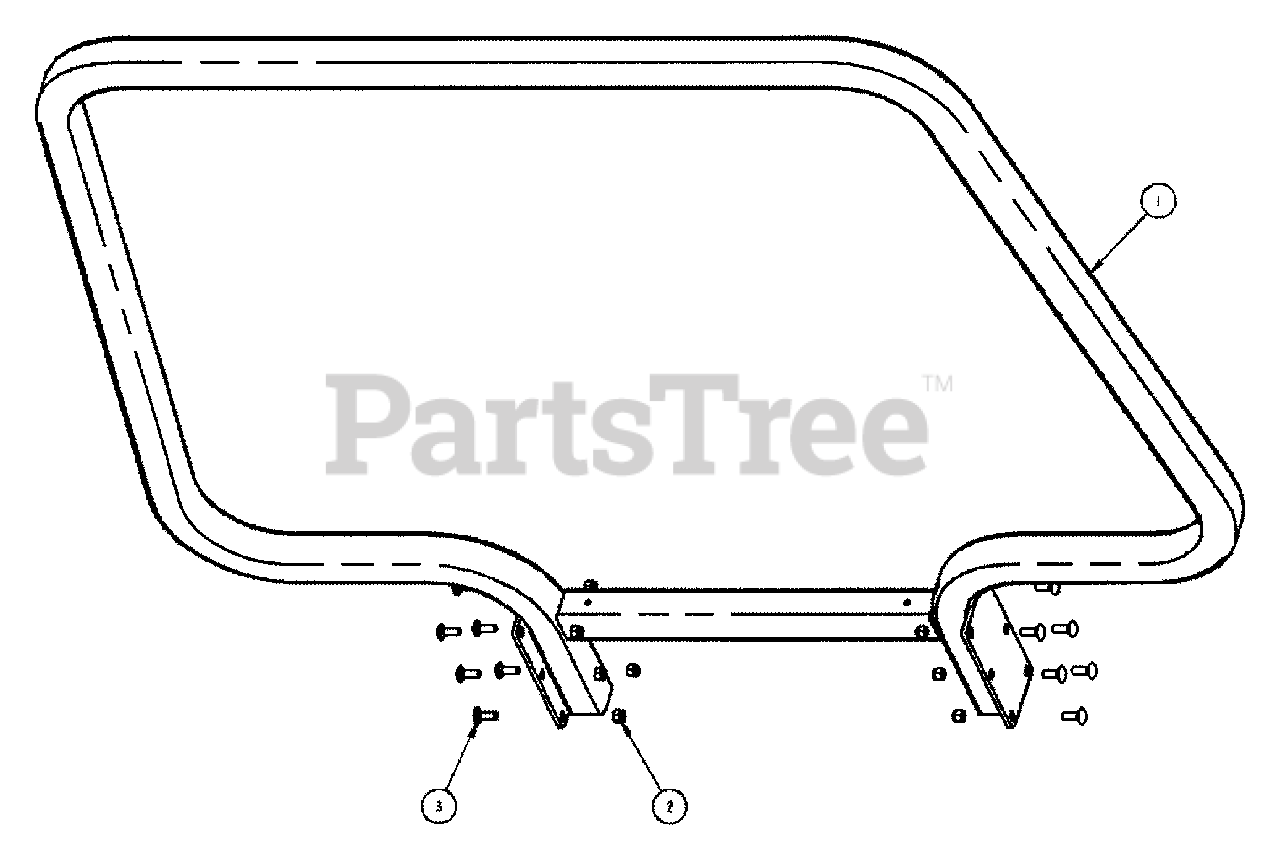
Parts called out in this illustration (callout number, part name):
1	WELDMENT, R.O.P.S.
2	HNYL, 3/8-16, YZ
3	RHSNB 3/8-16X1 YZ
